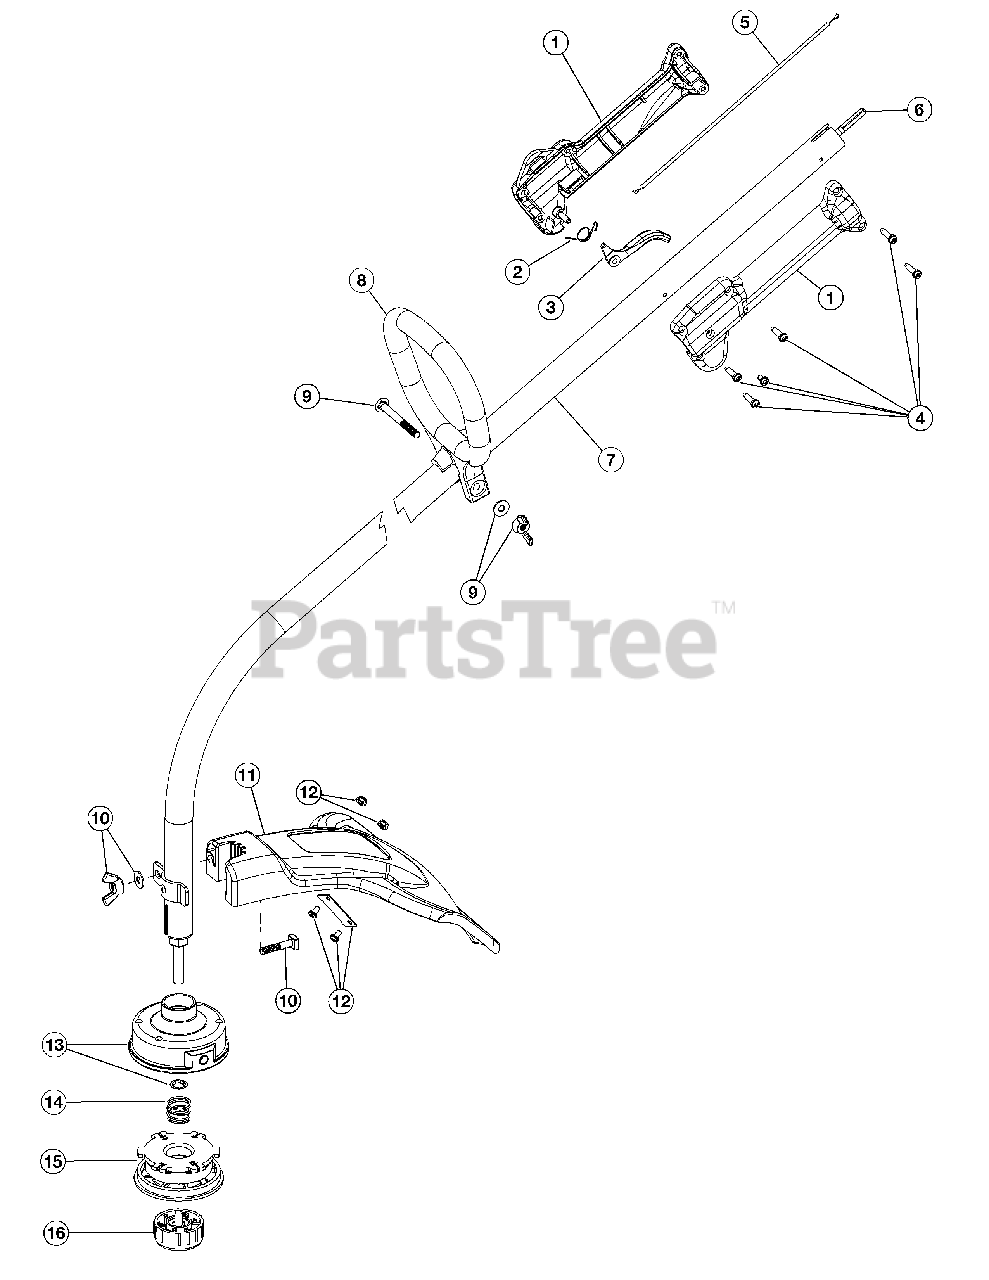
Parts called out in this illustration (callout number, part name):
1	Throttle Housing Assembly (includes 2-4)
2	Throttle Trigger Spring
3	Throttle Trigger
4	Throttle Housing Screws
5	Throttle Cable
6	Flexible Drive Shaft
7	Drive Shaft Housing
8	D-Handle Assembly (includes 9)
9	D-Handle Hardware
10	Guard Mounting Hardware
11	Guard Assembly (includes 12)
12	Blade Assembly
13	Outer Reel w/Retainer
15	Inner Reel
16	Bump Knob
